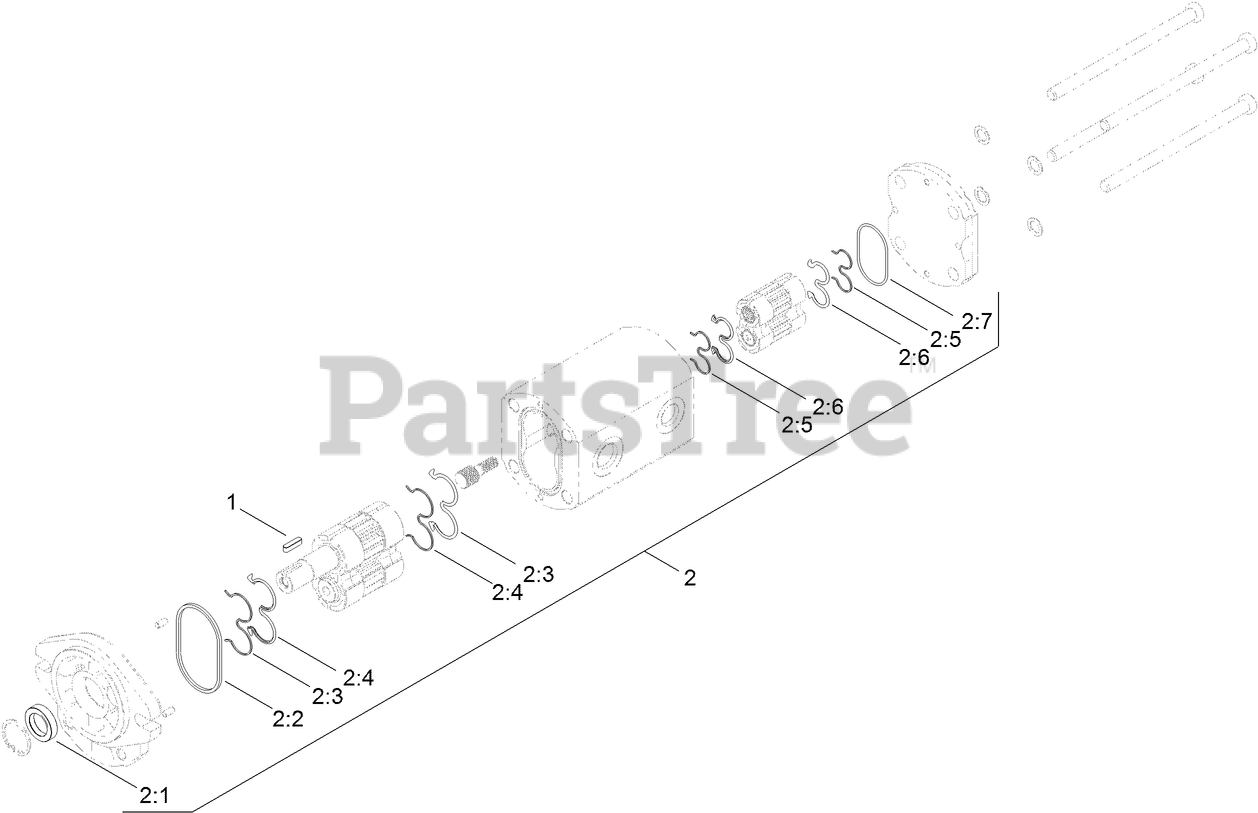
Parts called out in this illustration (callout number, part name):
1	KEY-SQUARE
2	SEAL KIT
2:1	SEAL-Shaft
2:2	SEAL-SQUARE
2:3	HUB and BEARING ASM
2:4	HUB and BEARING ASM
2:5	HUB and BEARING ASM
2:6	SEAL-GEAR-REAR
2:7	HUB and BEARING ASM
